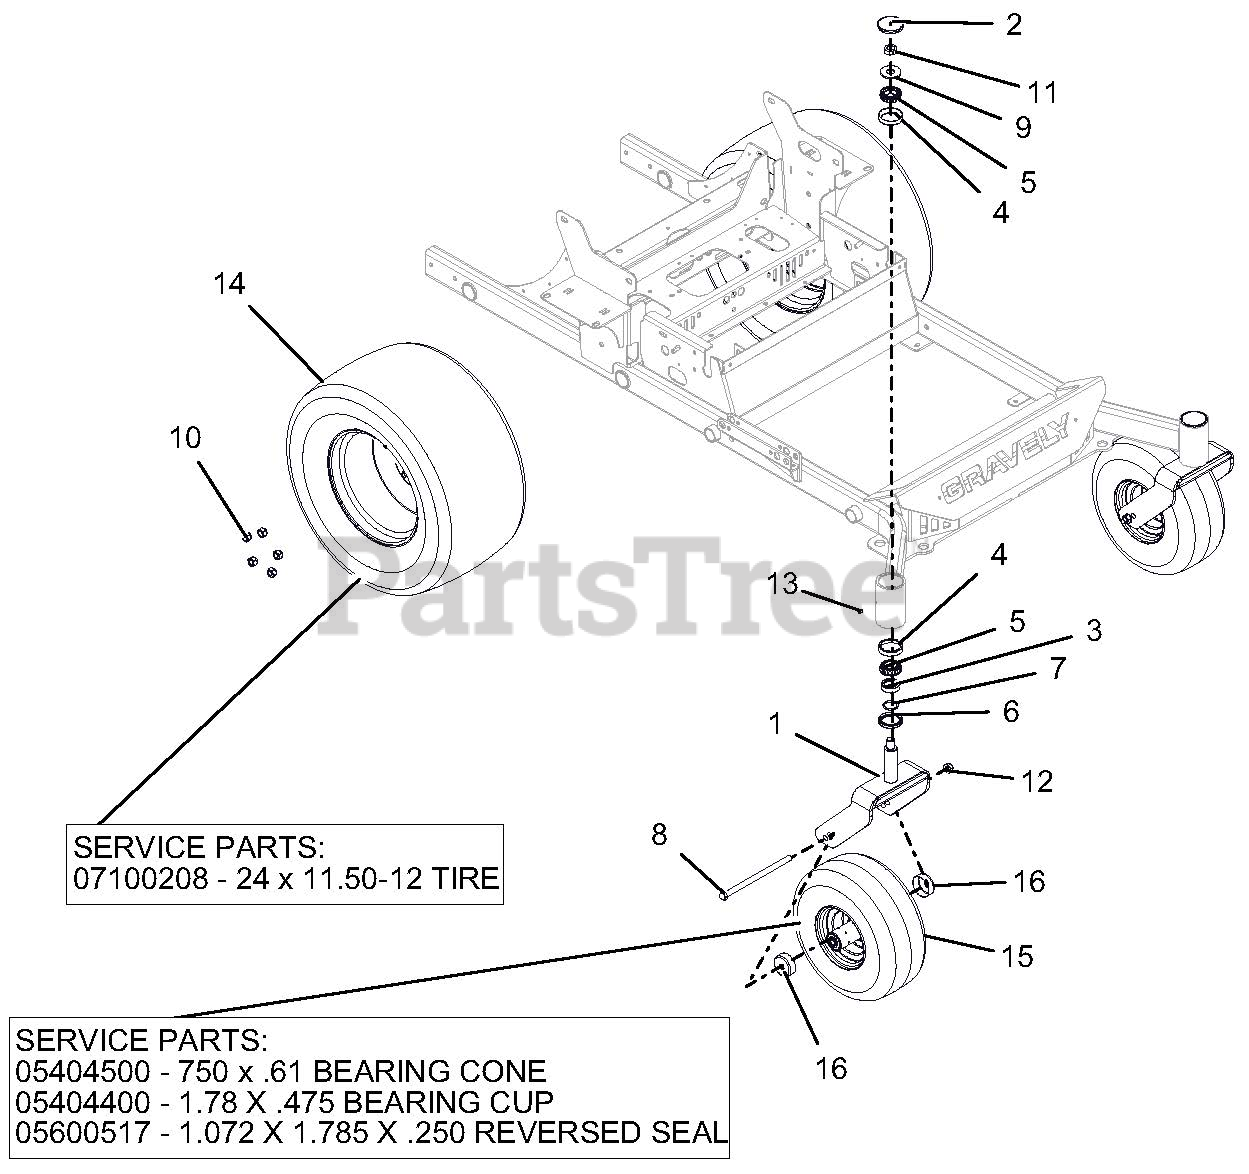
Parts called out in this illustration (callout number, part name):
1	WMT, CASTER FORK
2	CAP, DUST
3	SPCR, FRONT CASTER FORK
4	BRG, CUP 2.328 X .465
5	BRG, CONE 1.250 X .660
6	SEAL, OIL 1.75 X 2.332 X .312
7	O-RING, .139 W X 1.234 ID
8	BLT-HEX .50-13X9.00 GR5 YWZC
9	WSHR-FL-STL.812X2.00X.148YWZC
10	NUT, LUG .500-13
11	@NUT-LK-CTR-JAM .75-16 YWZC
12	NUT, LK-TOP-FLG .50-13 YWZC
13	FITTING, .250-28 FLUSH MOUNT GREASE
14	TIRE/WHEEL, ASM 24X11.50-12
14	24 X 11.50-12 TIRE
15	TIRE/WHEEL, 15 X 6.00-6 SEMI-PNEU
15	750 X .61 BEARING CONE
15	1.78 X .475 BEARING CUP
15	13072 X 1.785 X .250 REVERSED SEAL
16	SHIELD, WHEEL BEARING
